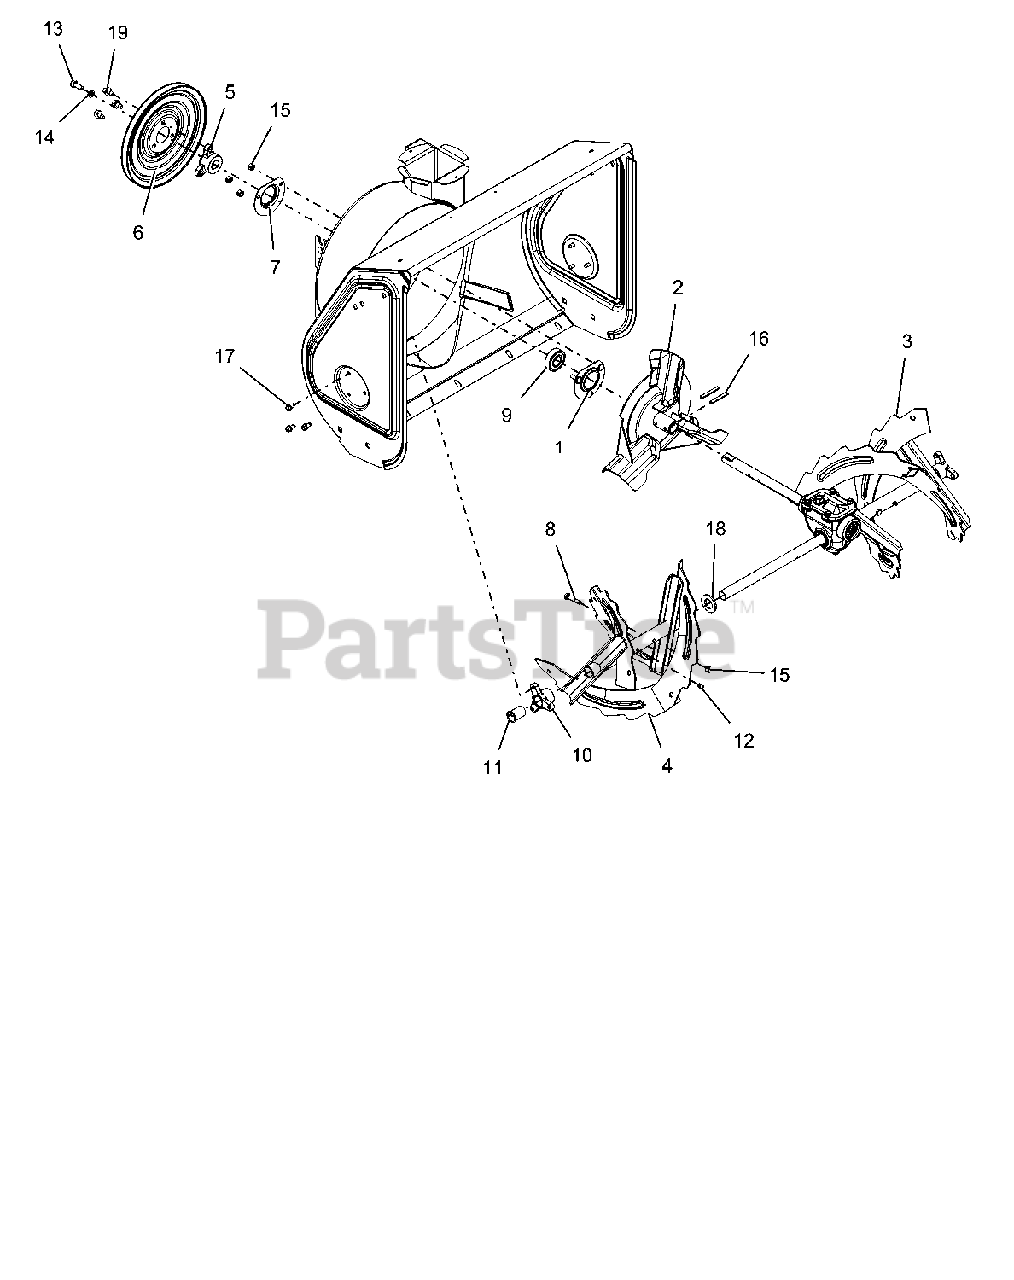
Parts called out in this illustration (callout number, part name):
1	BEARING FLANGE
2	IMPELLER, COMPACT 12" 3-BLADE
3	RAKE, 24" LH, BLK SERR W/ZERK
4	RAKE, 24" RH, BLK SERR W/ZERK
5	PULLEY HUB, BOLT-ON D-BORE .75
6	PULLEY,SPIN FORM SINGLE GROOVE
7	BEARING FLANGE
8	SHEAR BOLT WITH NUT
9	BRG-BALL .750X1.750X.50
10	BUSHING, RAKE SHAFT .75"
11	BSHG-FLG SPLIT NYLINER .75"ID
12	ZERK,FITTING .25X.125 DRIVE IN
13	BLT-HEX .31-24X.75 YWZC GR5
14	WSHR-LK .312X.097 HVY YWZC
15	@NUT-LK-CTR .25-20 YWZC
16	PIN-ROLL .250X1.75
17	SCR-TAP .25-20X.50 HWH TR YWZ
18	@WSHR-FL-STL.812X1.50X.135YWZC
19	@SCR-TAP .31-18X.50 HWH TR YWZ
